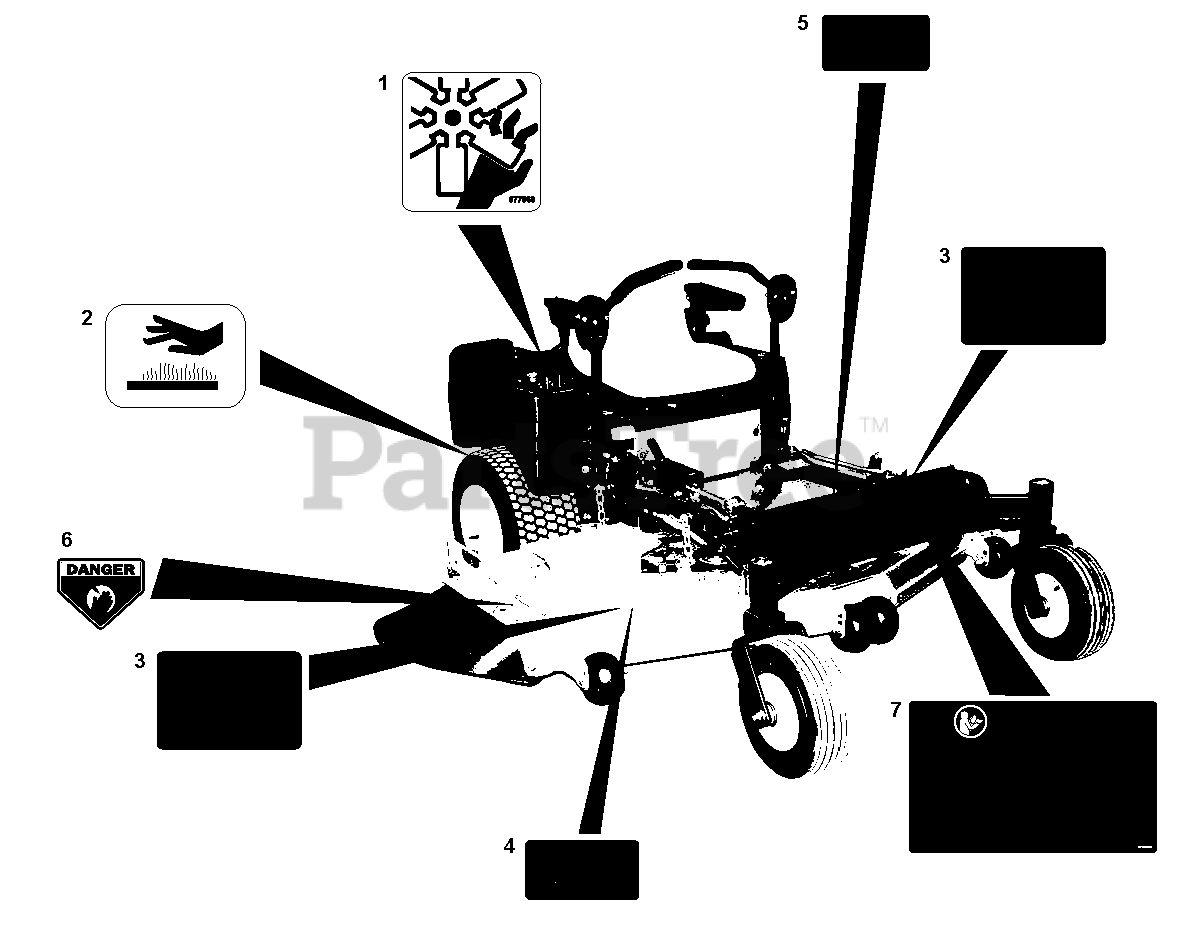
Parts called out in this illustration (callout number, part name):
1	Decal, Danger Fan
2	Decal, Hot Surface
3	Decal, Mower Safety
4	Decal, Safety Deck, Guarding
5	Decal, Safety Guarding
6	Decal, Danger
7	Decal, Safety, Main
